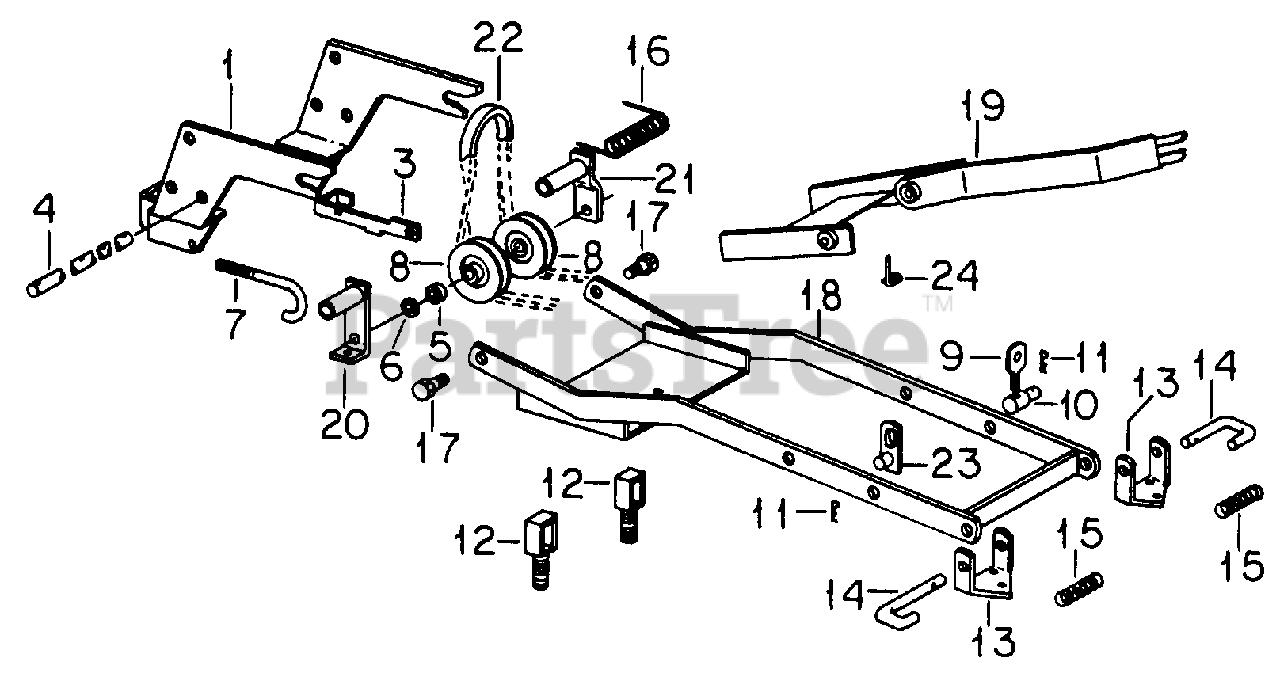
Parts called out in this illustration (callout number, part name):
1	Hanger Assy, Front
3	Support, Idler -Ratchet
4	Shaft, Idler Pivot
5	Spacer, .390 X .625 X .500
6	Washer, Wave
7	Bolt, Idler Adjuster
8	Pulley, Drive Belt Idler
9	Link, Adjustable
10	Block, Adjustable
11	Pin, Quick Attachable Cotter
12	Hanger, Mower Support Front
13	Bracket, Mower Support
14	Pin, Mower Support
15	Spring, Mower Support Pin
16	Spring, Mule Drive Idler
17	Bolt, Shoulder
18	Frame Assy, Outer Lift
19	Frame Assy, Center
20	Arm Assy, LH Idler
21	Arm Assy, RH Idler
22	Belt, Mule Drive -82 Series
23	Not used in this application
24	Not used in this application
